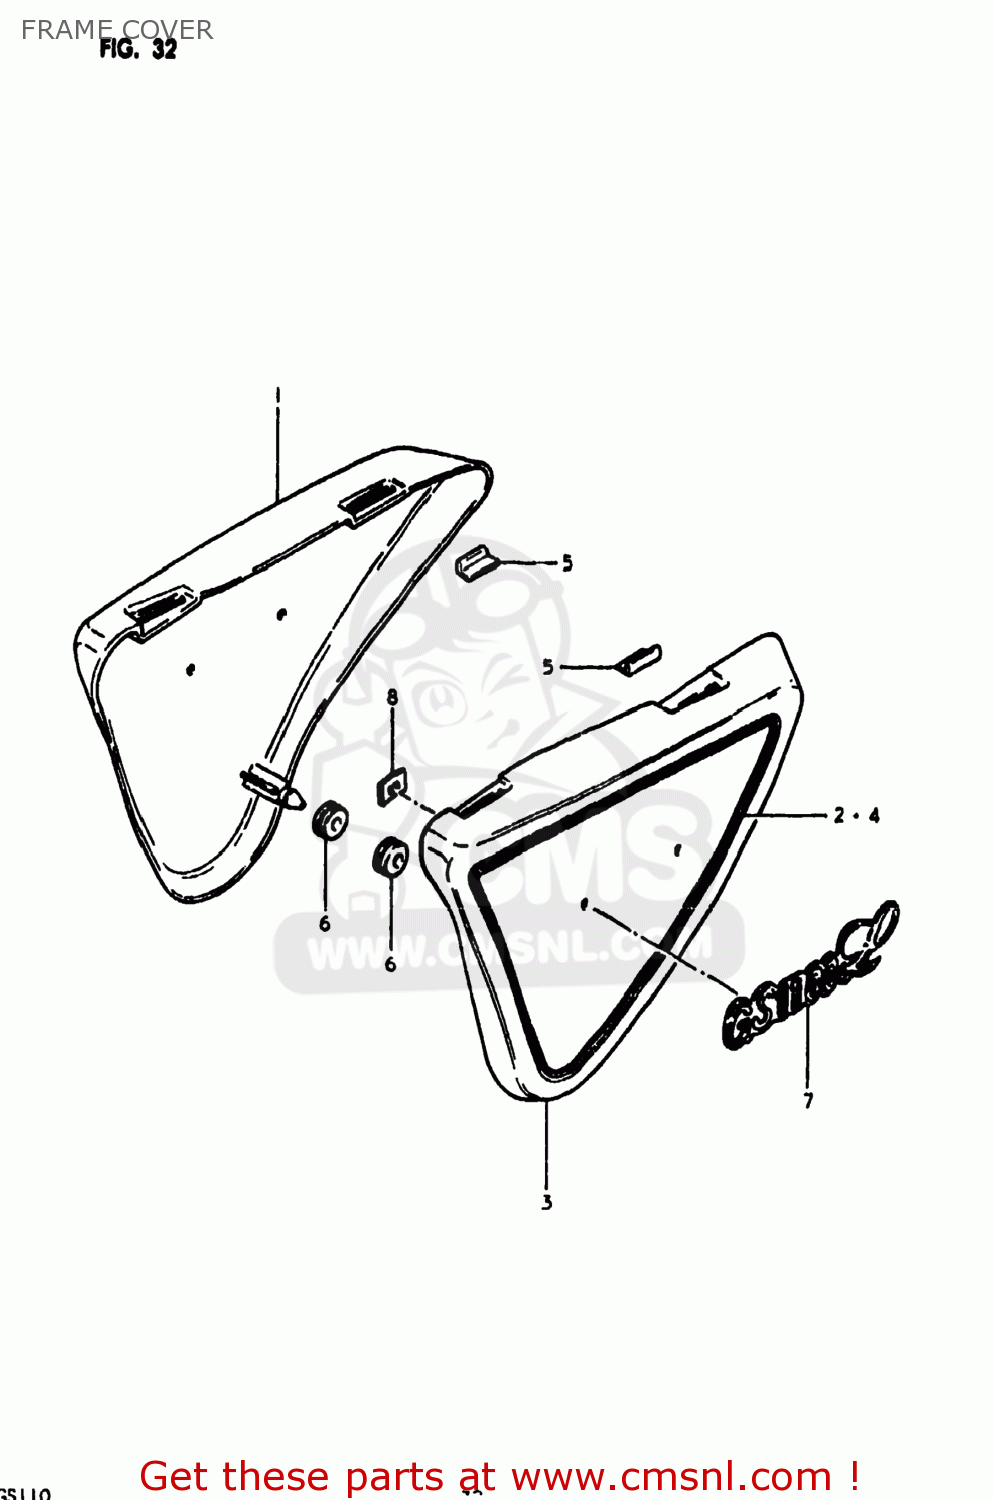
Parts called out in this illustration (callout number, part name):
1	COVER,FRAME,RIGHT
2	TAPE SET,FRAME COVER
3	COVER,FRAME,LEFT
4	TAPE SET,FRAME COVER
5	CUSHION,FRAME COVER
6	CUSHION
7	EMBLEM.FRM COVE
8	NUT
